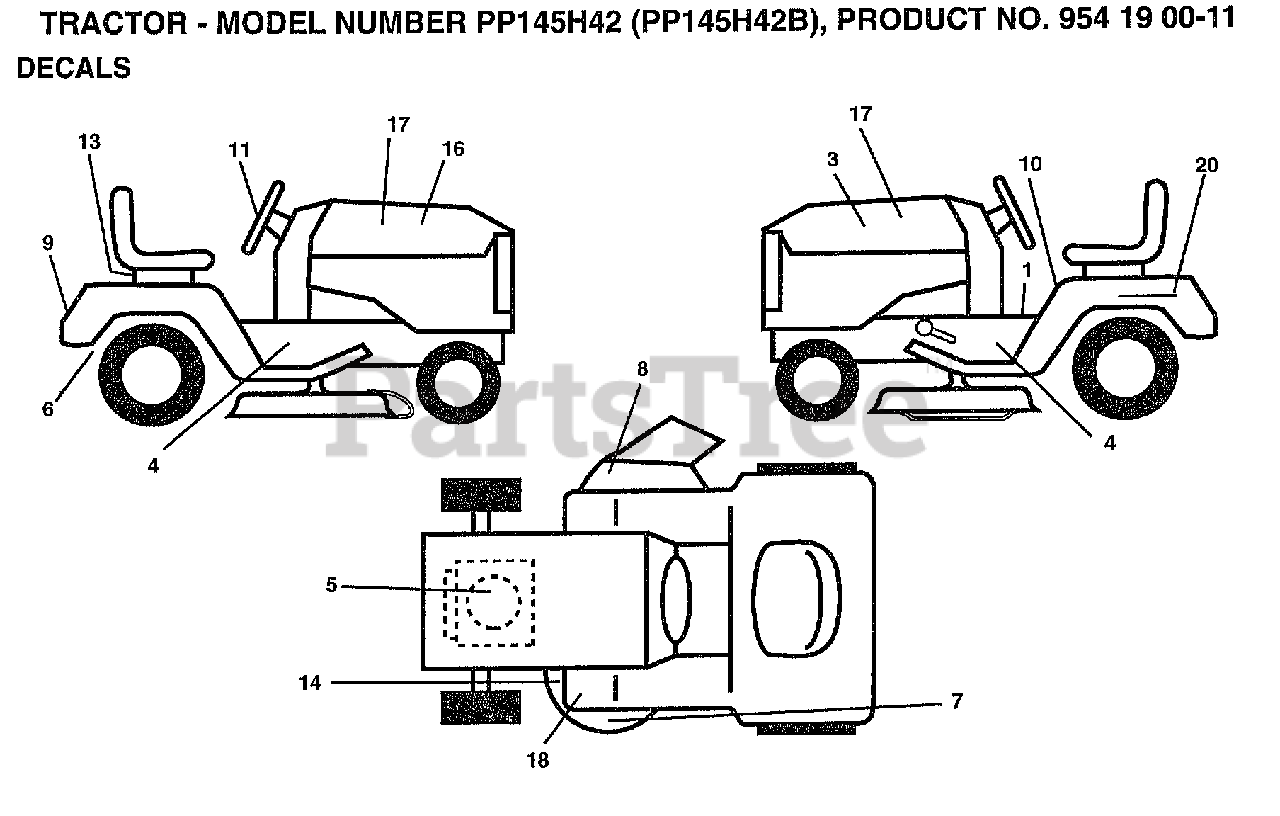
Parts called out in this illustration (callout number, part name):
1	DECAL SADDLE OPER
3	DECAL HOOD LH
4	"DECAL CHASSIS 42"""
5	DECAL HP ENGINE
6	DECAL DRAWBAR LH
7	"DECAL,ENVIRO DECK"
8	"DECAL, WARNING"
9	DECAL, FENDER
10	DECAL.CAUT.ENG/FR
11	DECAL, SCL COLD START HYD
13	RETAINER-SPRING
14	"DECAL-SCHEM,BELT"
16	DECAL HOOD RH
17	DECAL DOMED
18	DECAL T
20	DECAL.BATRY.3-3908
